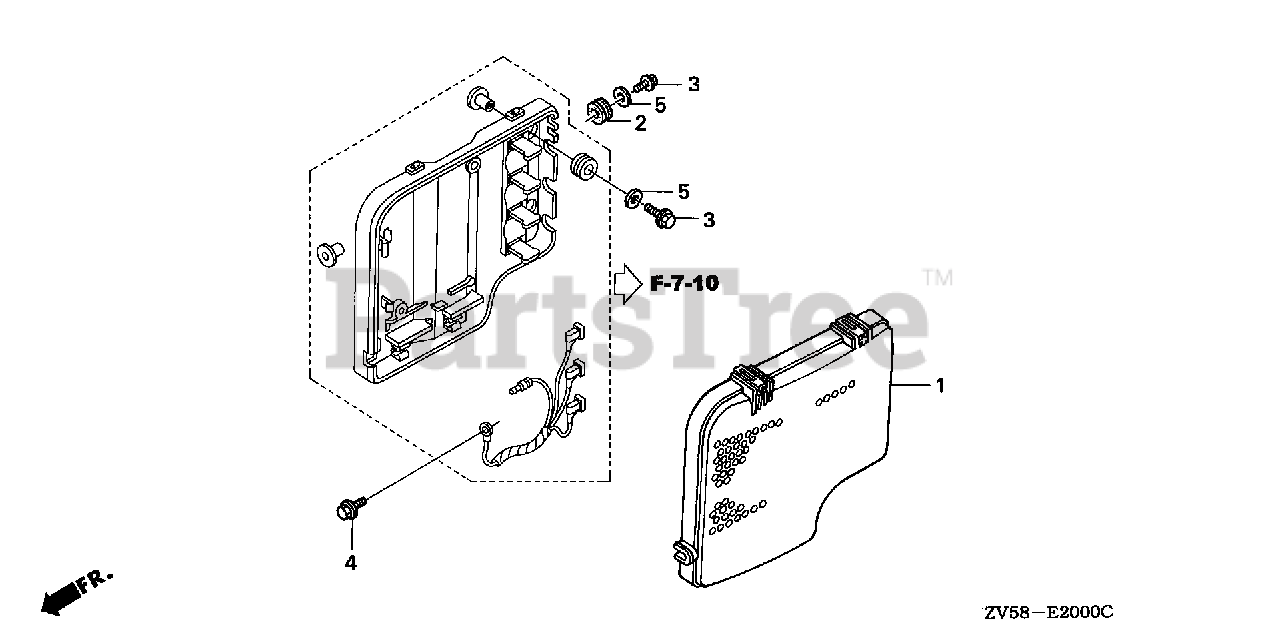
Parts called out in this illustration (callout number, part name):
1	COVER, IGNITION CONTROL MODULE (CDI)
3	BOLT, FLANGE (6X25)
4	BOLT, FLANGE (6X12)
4	BOLT, FLANGE (6X12) (CT200)
5	WASHER, PLAIN (6MM)
